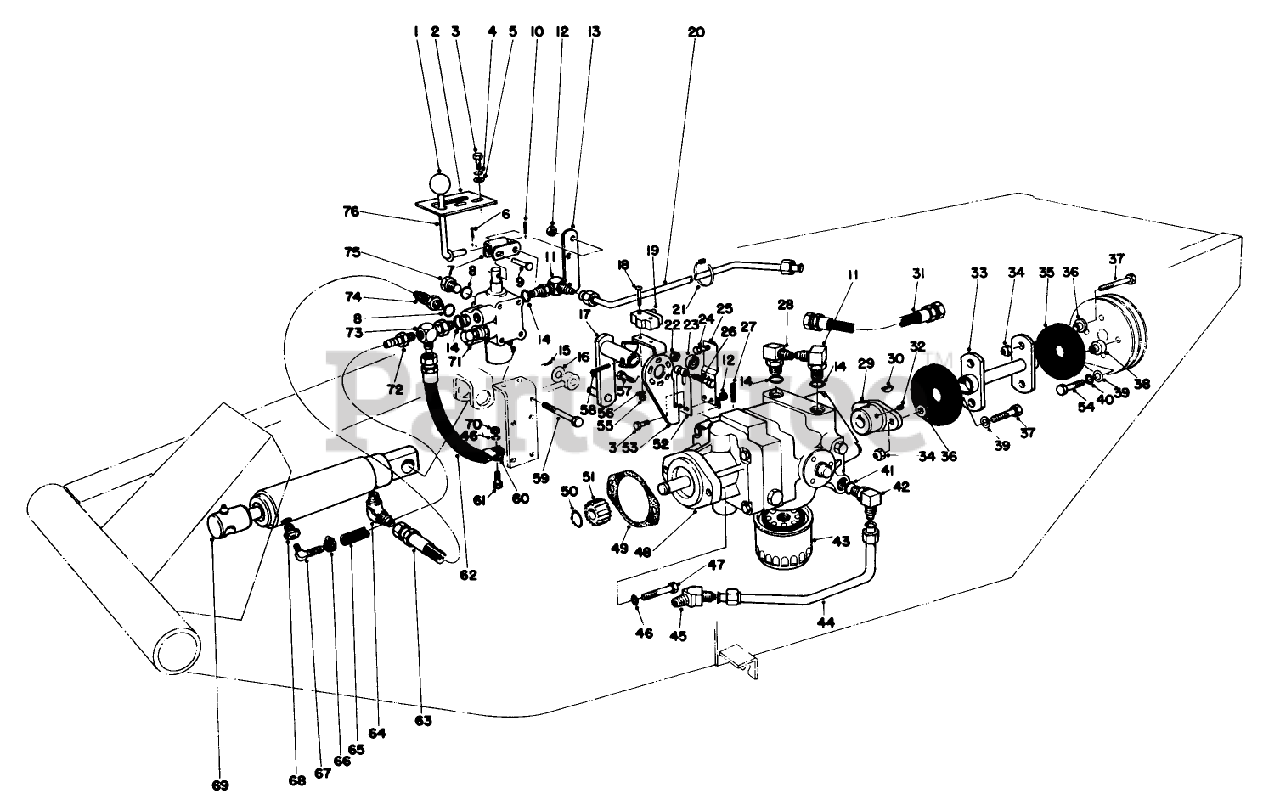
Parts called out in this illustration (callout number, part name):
2	LATCH-LEVER, VALVE
3	SCREW-HH
4	WASHER-LOCK
5	WASHER-FLAT
6	PIN-COTTER
7	Link-Valve Lever
8	O-RING
9	PIN-CLEVIS
10	PIN-ROLL
11	FITTING-ELBOW, 90 DEG
12	NUT-LOCK, NI
13	LEVER-VALVE, PIVOT MOUNT
14	O-RING
15	PIN-COTTER
16	WASHER-FLAT
17	Lever-Pump
18	SCREW-MACHINE
19	Micro Switch
20	PRESSURE LINE TUBE
21	TIE-CABLE
22	NUT-LOCK, NI
23	BEARING-BALL
24	SCREW-HH
25	EXTENDED LEAF SPRING ASM
26	SCREW-HH
27	PIN-ROLL, SLOTTED
28	FITTING-HYD, 90 DEG
29	HUB-PUMP
30	KEY-WOODRUFF
31	PUMP-COOLER HOSE
32	SCREW-SET, HSH
33	Drive Coupling
34	NUT-LOCK, CONE
35	Coupling Rubber
36	SPACER-COUPLING
37	SCREW-HH
38	SPACER-RUBBER COUPLNG
39	WASHER-FLAT
40	WASHER-LOCK
41	O-RING
42	FITTING-ELBOW, 90 DEG
43	FILTER-OIL, TRANSMISSION
44	AXLE-PUMP TUBE ASM
45	45 DEG FITTING
46	WASHER-LOCK
47	SCREW-HH
48	Transmission Inline (Incl. Ref. #30 & 51)
49	Gasket
50	Ring-Snap
51	Gear
52	SPRING-LEAF
53	Plate-Pump
54	SCREW-HH
55	NUT-HEX
56	WASHER-LOCK, INTERNAL
57	1/4-20 X 3/4 THDG SCR
58	PIN-SPRING
59	SCREW-HH
60	CLAMP-R
61	SCREW-HH
63	VALVE-CYLINDER HOSE
64	ELBOW
65	GAS LINE
66	CLAMP-HOSE
67	CONNECTOR-HOSE
68	REDUCING BSGH
69	Hydraulic Cylinder
70	NUT-HEX
71	Valve
72	FITTING-STRAIGHT
73	FITTING ASM
74	FITTING-ELBOW, 90
76	Lever Valve
